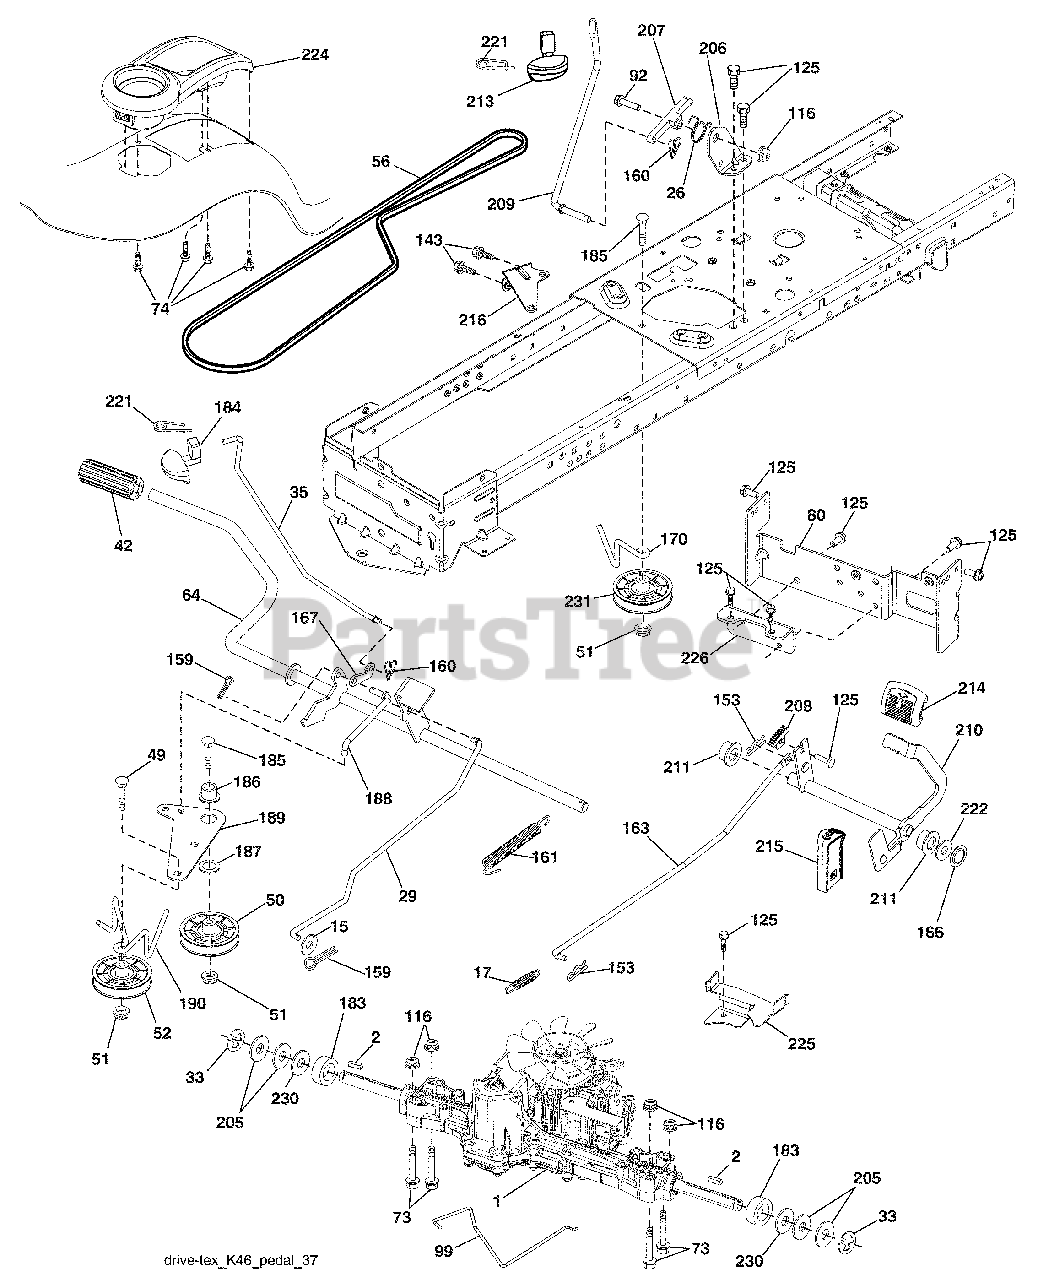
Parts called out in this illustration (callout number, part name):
1	Transaxle, Tufftorq K46BT
2	Key Square
15	Washer 13/32 x 13/16 x 16 Ga.
17	Spring, Brake
26	Spring Return Cruise
29	Rod, Brake
35	Rod, Brake, Park
42	Cover, Foot Pedal
50	Pulley Idler Flat
51	Lock Nut 3/8-16
52	Idler V-Groove 910" Offset
56	V-Belt, Drive
64	Shaft Asm. Pedal Brake Control
73	Bolt Hex 5/16-18 Gr. 5
74	Screw Hex Wsh Hi Lo 1/4 x 1/2 unc
80	Strap Torque
92	Bolt Fin Hex 5/16-18 unc x 1.25
99	Rod Spring Bypass
114	Nut Lock HX w/Ins 5/16-18
116	Nut Lock Hex Flange 5/16-18
125	Screw 5/16-18 x 3/4
143	Screw 5/16-18 x 1/2
153	Retainer Spring 1"
159	Pin Cotter 1/8 x 3/4
160	Retainer Clip
161	Spring, Return, Clutch
163	Rod Control
166	Nut Push
167	Latch Brake Parking
170	Keeper V-Idler
183	Spacer Axle
184	Handle Parking Brake
186	Spacer Retainer
187	Washer
188	Link Clutch Ground Drive
189	Bellcrank Ground Drive
190	Keeper Bellcrank Ground Drive
205	Washer 25/32 x 1-5/8 x 16 Ga.
206	Bracket Mount Latch Cruise
207	Latch Control Cruise
208	Gear Sector Control Cruise
209	Rod Control Cruise
210	Rocker Asm. Pedal Control
211	Bearing Nylon
213	Knob Control Cruise
214	Pedal Forward
215	Pedal Reverse
216	Bracket Pulley Idler
221	Retainer Spring Clip Handle
222	Washer 21/32 x 1-1/4 10 Ga.
224	Cupholder
225	Keeper Belt Transaxle
226	Bracket Mount Torque
230	Washer Harden .793 x 1.637 x 060
231	Idler V-Groove 1.688" Offset
